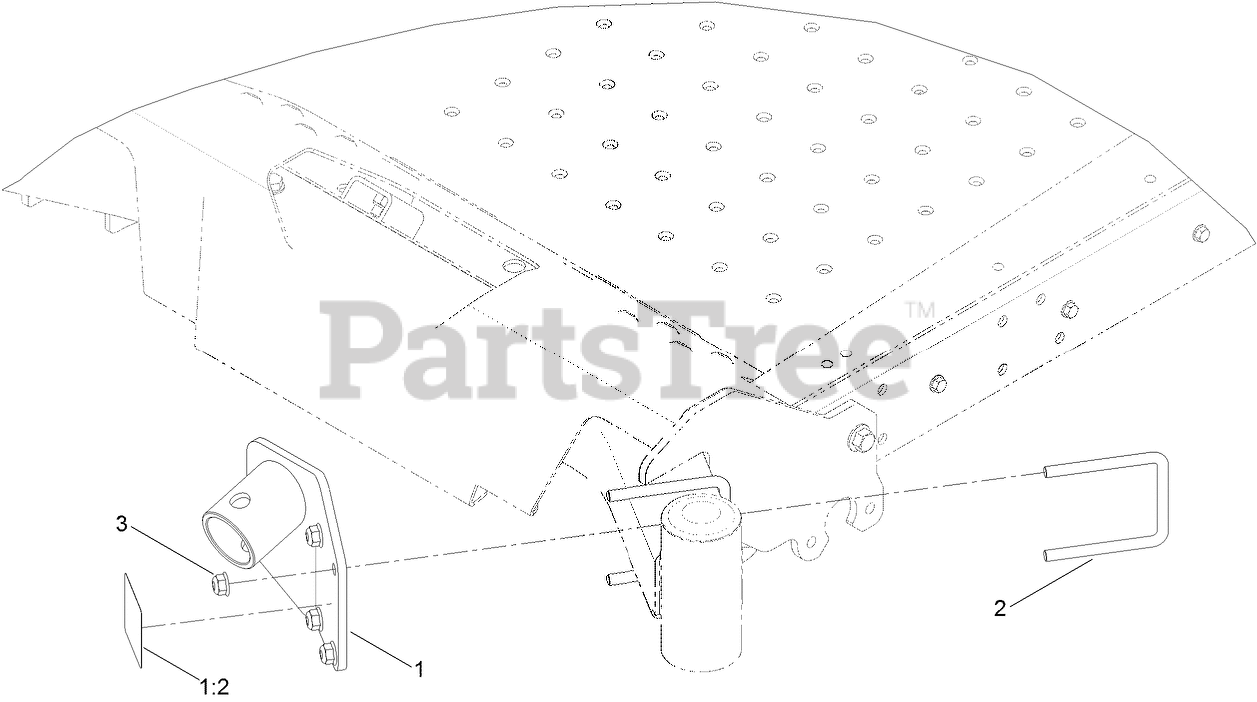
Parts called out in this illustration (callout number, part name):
1	JACK MOUNT ASM
1:2	DECAL-WARNING, JACK
2	U-BOLT
3	NUT-HF, NI
